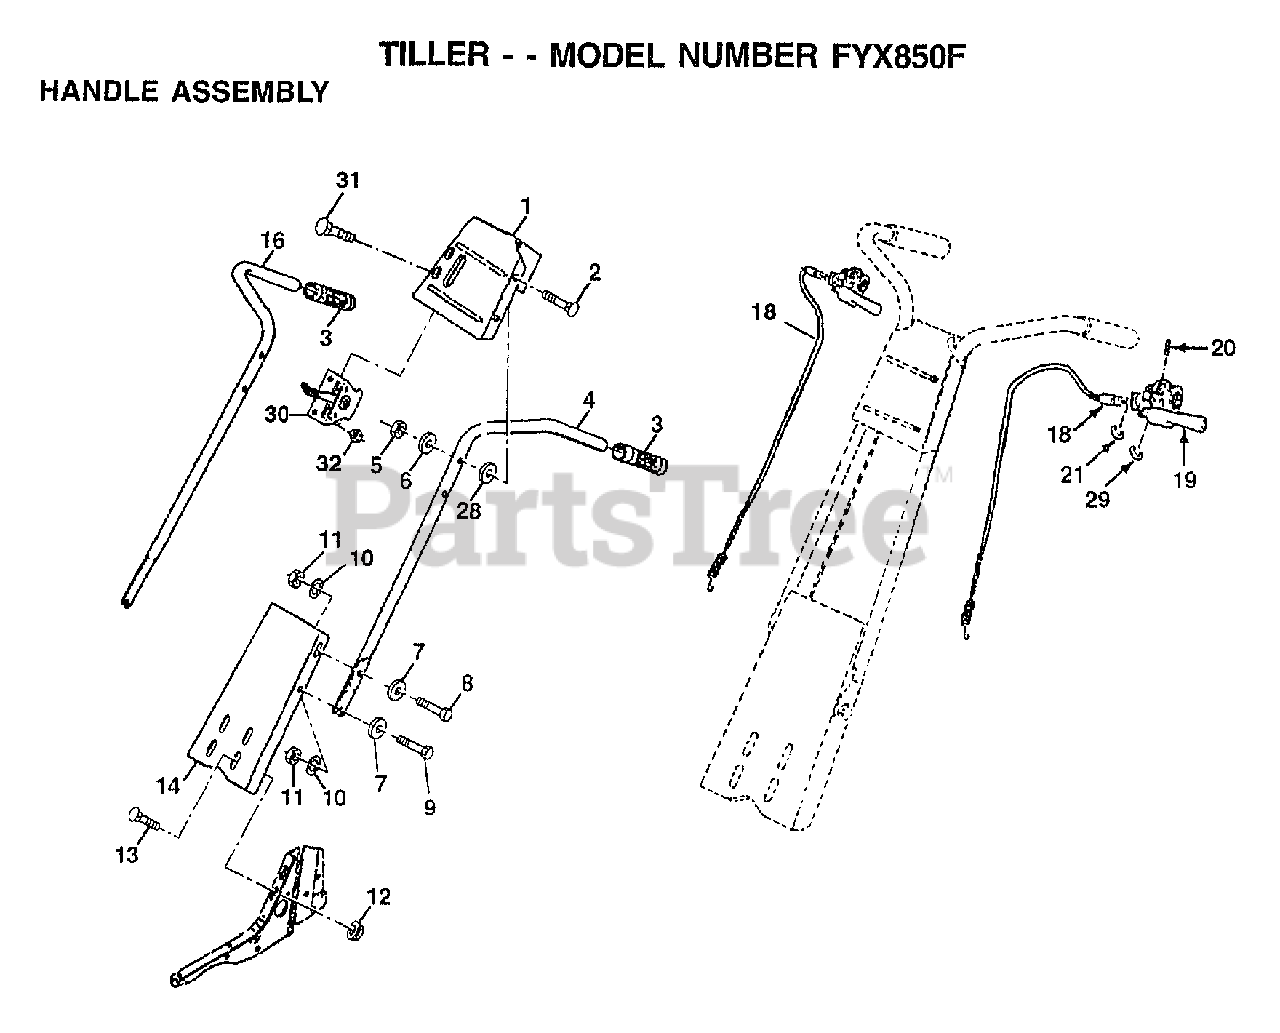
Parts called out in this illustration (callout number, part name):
1	BRACKET.HANDLE
2	BOLT
4	HANDLE.LH
6	WASHER
7	WASHER
9	BOLT
10	LOCKWASHER
11	NUT.HEX.5/16-18
12	NUT
13	BOLT
14	"PANEL, HANDLE"
16	HANDLE.RH.DOUBLE.BEND
18	CABL.CLUTCH.49.88
19	LEVER CONTRL TINE
20	"PIN PIVOT,GROOVED"
21	E-RING
28	WASHER
29	RETAINER RING
30	CONTROL THROTTLE
31	SCREW.PNHD.10-24
